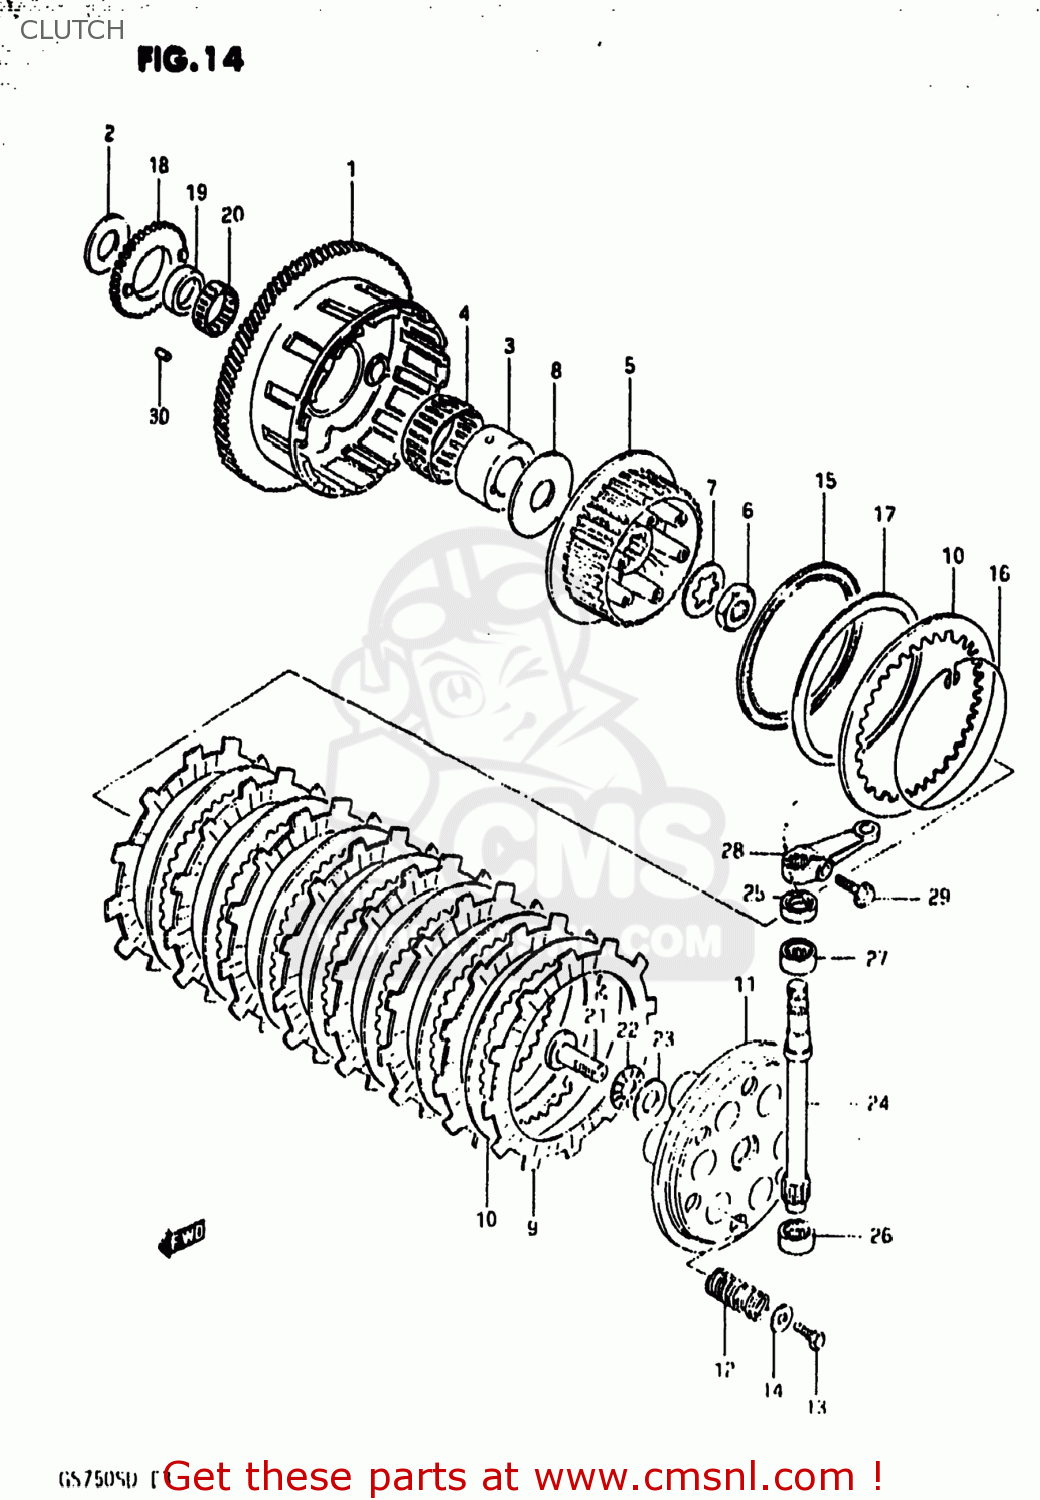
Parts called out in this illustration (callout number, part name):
1	GEAR ASSEMBLY,PRIMARY DRIVE
2	WASHER
3	SPACER
4	BEARING(51X56X28)
5	HUB,CLUTCH SLEEVE
6	NUT
7	WASHER,LOCK
8	WASHER(25X66X3.5)
9	PLATE,CLUTCH DRIVE (MCA)
10	PLATE,CLUTCH DRIVEN(T:2.0) (NAS)
11	DISC,CLUTCH PRESSURE
12	SPRING
13	BOLT, UPPER
14	WASHER
15	SEAT,WAVE WASHER
16	RING,STOPPER
17	WASHER
18	GEAR,ENG OIL PUMP DRIVE(NT:38)
19	SPACER,OIL PUMP DRIVE GEAR
20	BEARING(36X40X10)
21	RACK,CLUTCH RELEASE
22	BEARING(15X28X2)
23	WASHER
24	PINION,CLUTCH RELEASE
25	OIL SEAL
26	BEARING(12X19X12)
27	BEARING(15X22X12)
28	ARM,CLUTCH RELEASE
29	BOLT (6X20)
30	CUSHION,PRIMARY DRIVEN GEAR
